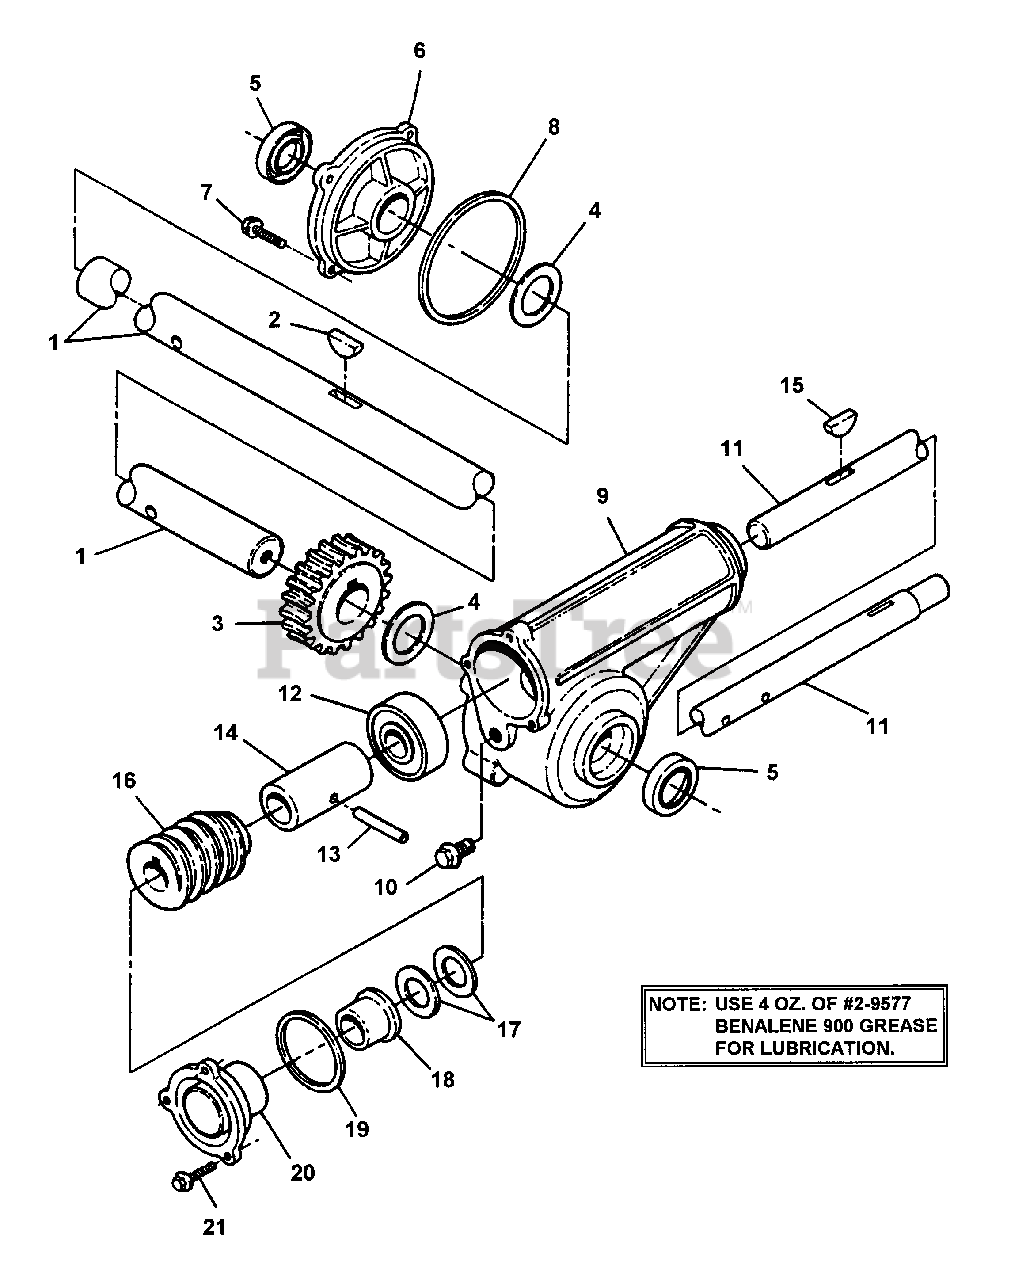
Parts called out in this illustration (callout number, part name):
1	SHAFT, Auger
2	KEY, 1/4 x 7/8" Woodruff
3	GEAR, Worm
4	WASHER, 1.0 x 1-1/2" Thrust
5	SEAL, 1-1/2" O.D. Oil
6	COVER, Gear Case
7	SCREW, 1/4-20 x 3/4" Hex Washer Self-Tap
8	O-RING, Case Cover
9	CASE, Gear
10	SCREW, 3/8-16 x 1/2" Hex Washer Self-Tap
11	SHAFT, Impeller
12	BEARING, Impeller Shaft
13	PIN, 1/4 x 1-1/2" Roll
14	SPACER, Gear Bearing
15	KEY, 3/16 x 7/8" Woodruff
16	GEAR, Rolled Worm
17	WASHER, 3/4 x 1-1/8" Thrust
18	BUSHING, Impeller Shaft
19	O-RING, Case Cap
20	CAP, Case
21	SCREW, #10-24 x 5/8" Hex Washer Self-Tap
